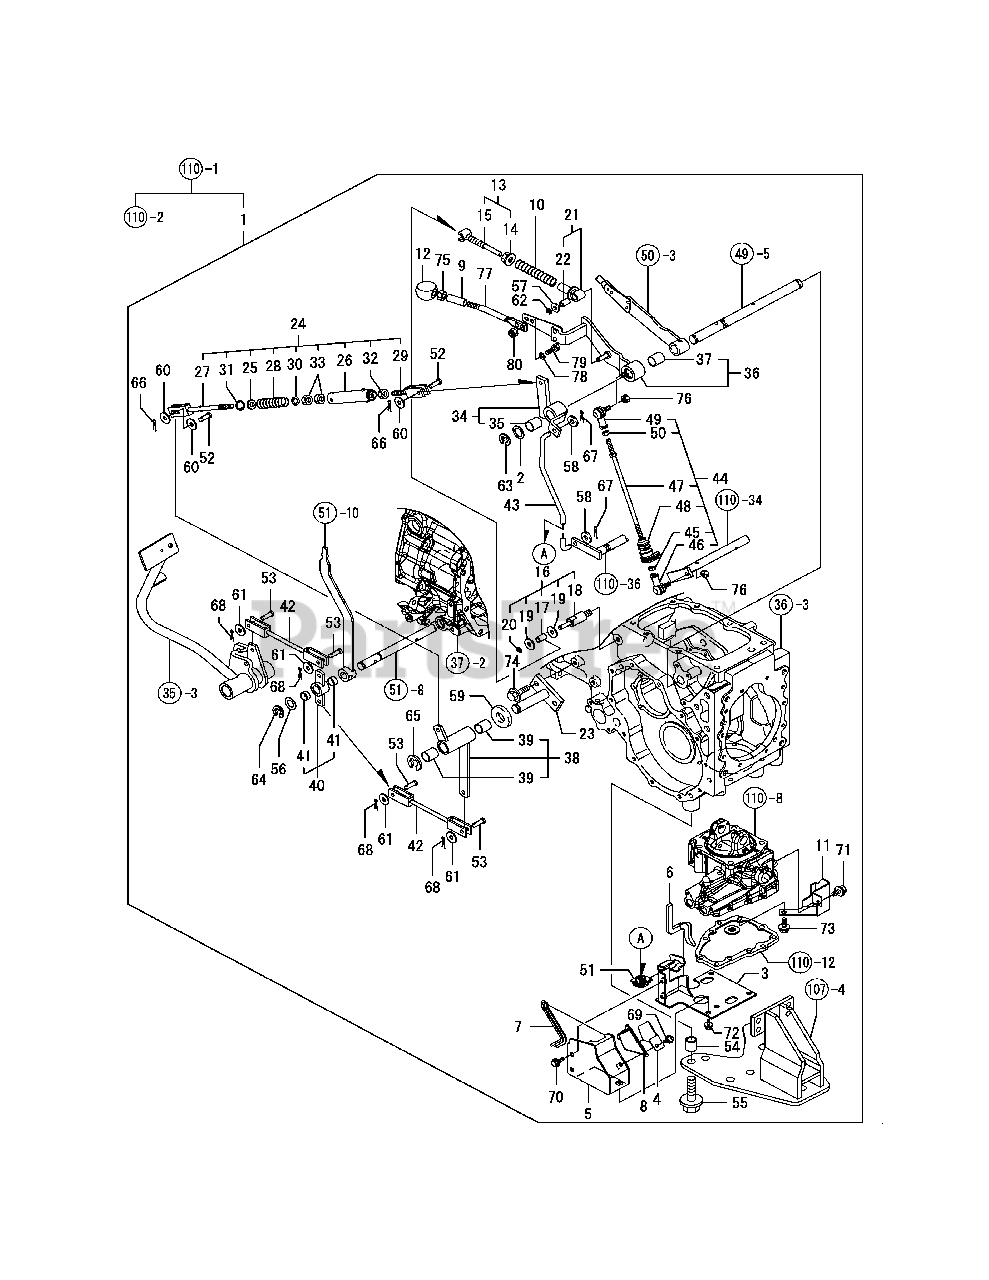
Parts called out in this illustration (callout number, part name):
1	MID PTO, EXTERIOR KIT
2	SPACER 20X30X1.6
3	COVER (A), MID PTO
4	COVER (C), MID PTO
5	COVER (B), MID PTO
9	HOSE, PROTECTION
10	SPRING, MID PTO
12	KNOB, MID PTO LEVER
13	SPRING SUPPORT ASSY
21	SPRING END ASSY
24	SPRING CAPSULE ASSY
26	HOLDER, SPRING
27	ROD,MID PTO BRAKE
29	JOINT (RH SCREW)
34	BELL-CRANK ASSY
36	LEVER, MID PTO CMP
40	ARM, MID PTO ASSY
42	ROD, MID PTO BRAKE
43	ROD, MID PTO BRAKE
45	NUT W/WASHER 8
49	BEARING, ROD-END
54	COLLAR 17X25X22
55	BOLT M16X 55 PLATED
56	LINER 17.2X30X1
57	WASHER 8, POLISHED
58	WASHER 10, POLISHED
59	WASHER 20, POLISHED
66	COTTER PIN 2.5X30
67	COTTER PIN 2.5X30
68	COTTER PIN 2.5X30
70	BOLT M 6X 12 PLATED
71	BOLT M 8X 16 PLATED
72	BOLT M 8X 20 PLATED
73	BOLT M 8X 20 PLATED
74	BOLT M10X 25 PLATED
75	NUT M10
78	SPRING WASHER 5
79	BOLT M 5X 16 PLATED
80	U-NUT, 5
